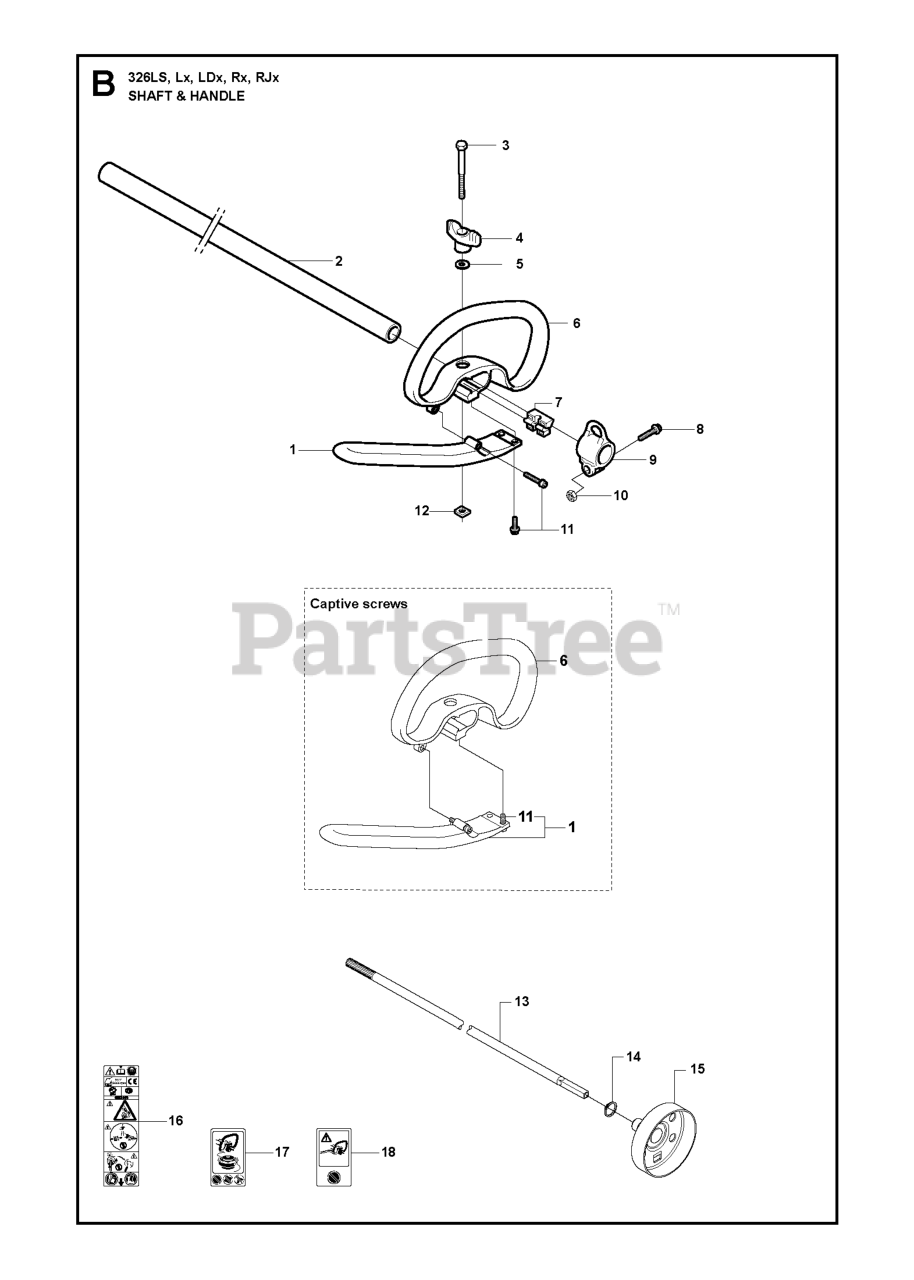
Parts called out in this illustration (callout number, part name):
1	HANDLE EXTENSION
1	HANDLE
2	DRIVE TUBE ASSEMBLY
3	SCREW
3	SCREW M6X50
4	KNOB
5	WASHER
6	HANDLE
6	HANDLE, LOOP
7	SPACER PLASTIC
8	SCREW
9	HARNESS HOLDER
10	NUT
11	SCREW
11	SCREW IHSCFTO
13	DRIVE SHAFT
14	RETAINING RING SGA 10
15	CLUTCH DRUM
16	RP WARNING DECAL
17	DECAL WARNING "NO BLADES"
18	DECAL
